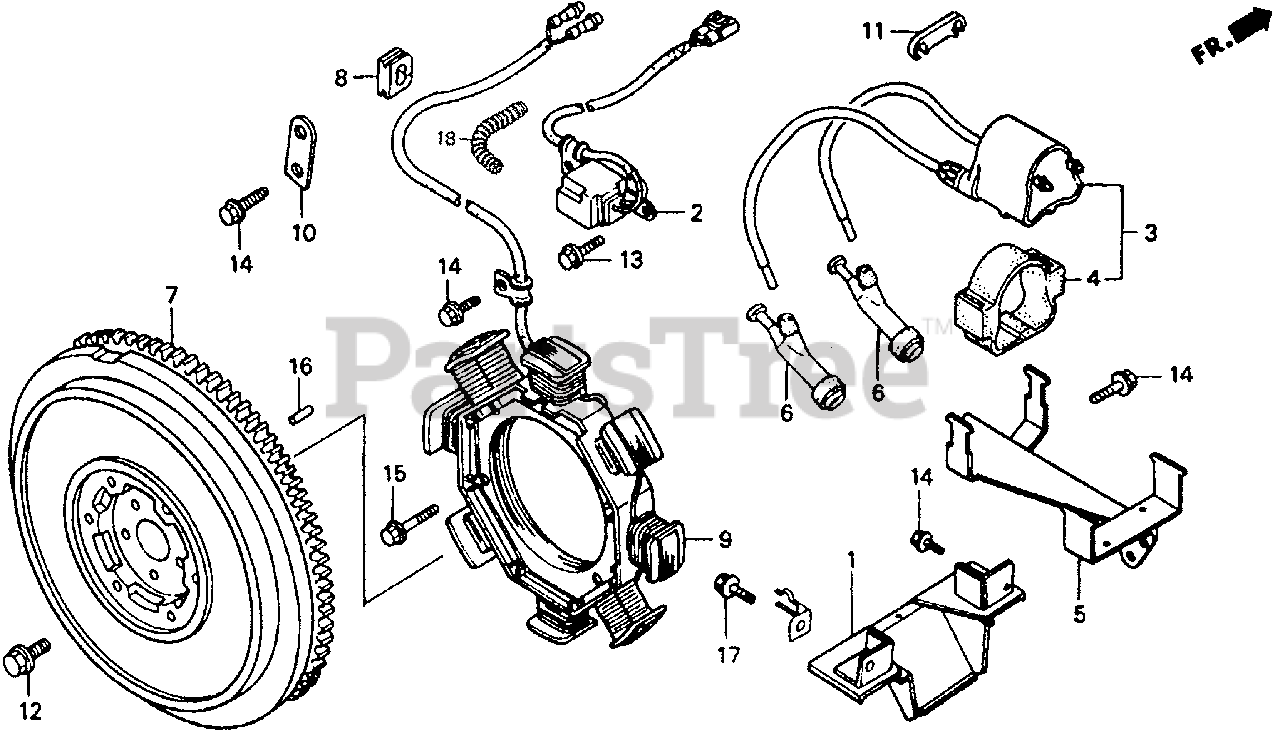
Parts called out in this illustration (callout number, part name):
1	PROTECTOR, HEAT (UPPER)
2	COIL ASSY., PULSER
3	COIL ASSY., IGNITION
4	SUSPENSION, IGNITION COIL
5	BRACKET, ELECTRIC PARTS
6	CAP ASSY., NOISE SUPPRESSOR
7	FLYWHEEL
8	GROMMET, WIRE
9	COIL ASSY., CHARGE
11	CLAMP, WIRE (Honda Code 0839837). (NOT AVAILABLE)
12	BOLT, HEX. (10MM)
13	BOLT, FLANGE (5X16)
14	BOLT, FLANGE (6X14)
15	BOLT, FLANGE (6X25)
16	PIN B, DOWEL (6X10)
17	BOLT, FLANGE (8X20)
18	TUBE, CORRUGATE
